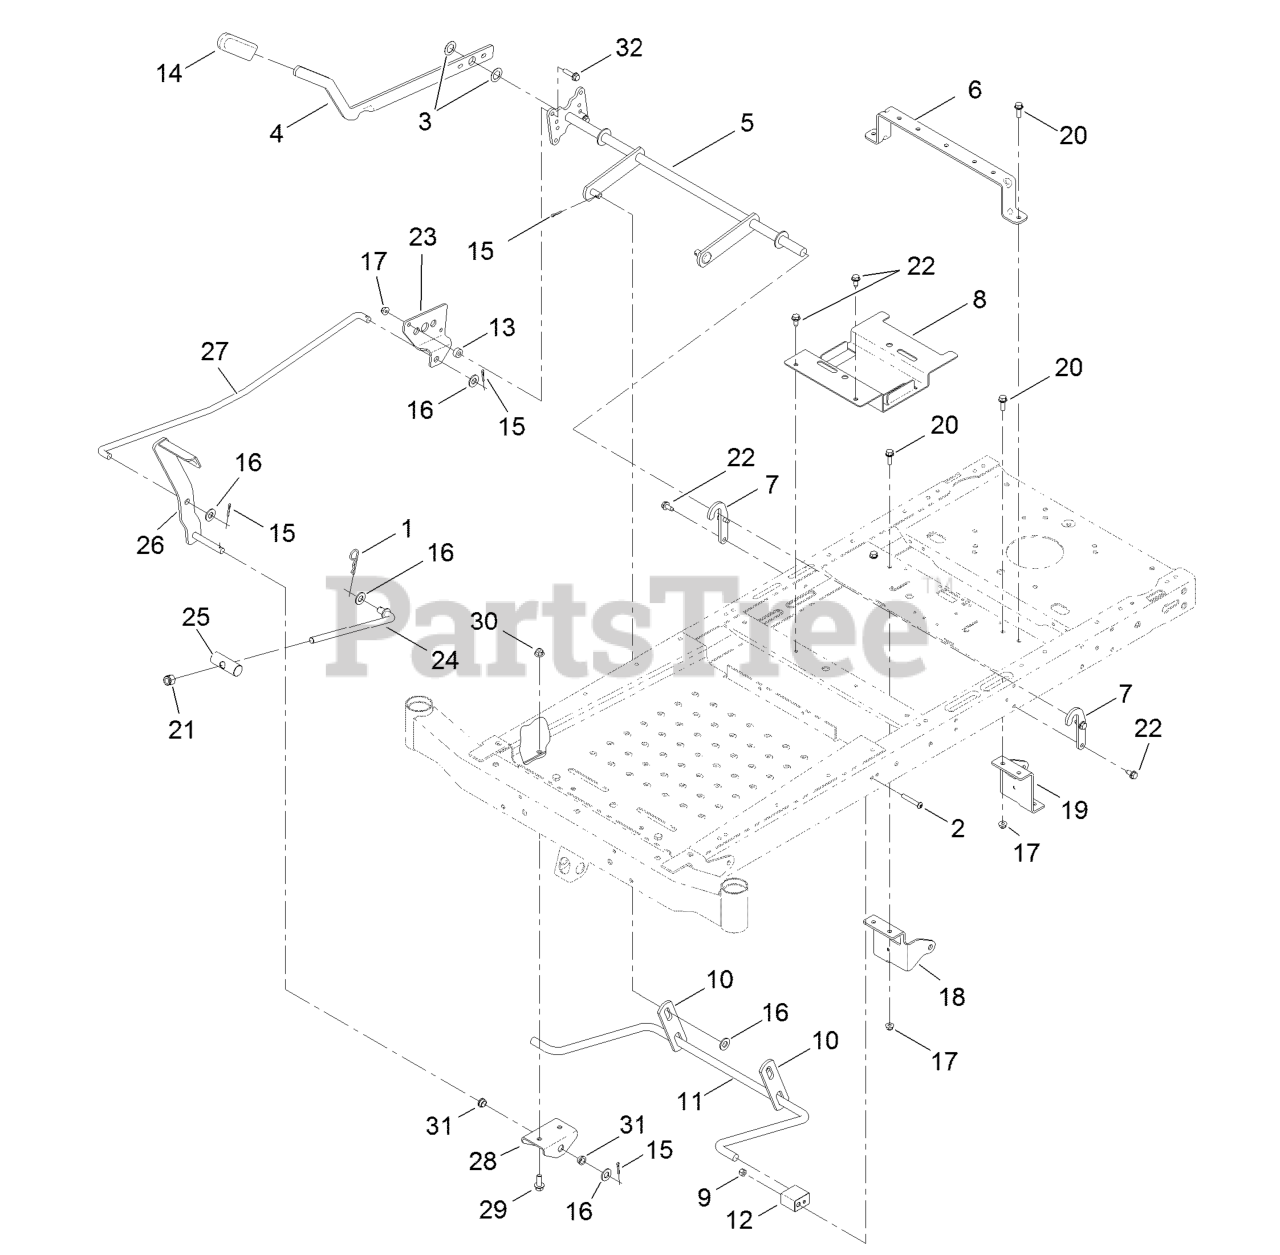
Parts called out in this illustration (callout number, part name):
1	PIN-COTTER
2	SCREW-HSBH
3	WASHER-THRUST
4	LEVER-LIFT
6	BRACE-SEAT, REAR
7	BRACKET-LIFT
8	BRACKET-BATTERY
9	NUT-LOCK, NI
10	LINK-LIFT
11	ARM-LIFT, REAR (WIDE)
12	BLOCK-PIVOT
14	GRIP-LEVER
15	PIN-COTTER
16	WASHER-FLAT
17	NUT-HF, NI
18	MOUNT-HYDRO, FRONT (RH)
19	MOUNT-HYDRO, FRONT (LH)
20	SCREW-HHF
21	NUT-HEX
22	Screw-HWH 5/16-18 X 3/4 Tf
23	PLATE-FOOTLIFT
25	PIN-PIVOT
26	PEDAL ASM
27	ROD-FOOTLIFT
28	BRACKET-FOOTLIFT
29	SCREW-HHF 3/8-16 X 1
30	NUT-HF, NI
31	BUSHING-FLANGE
32	SCREW-HHF
